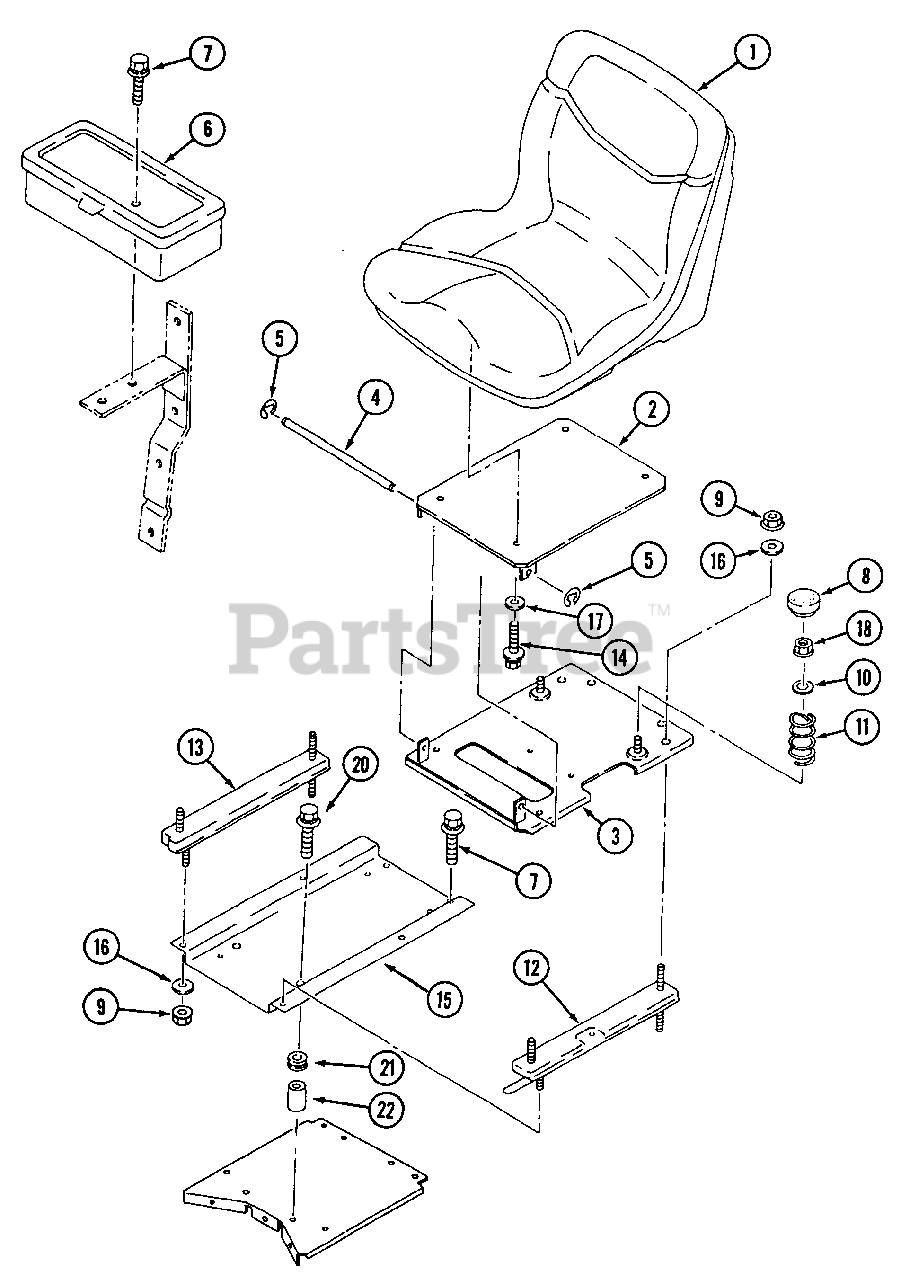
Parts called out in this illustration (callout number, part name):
1	Seat, Ass'y.
3	Bracket, Seat
9	Nut, 8 mm
11	Spring
12	Adjuster, Slide
13	Rail, Slide
16	Washer, Lock
17	Washer, Lock
